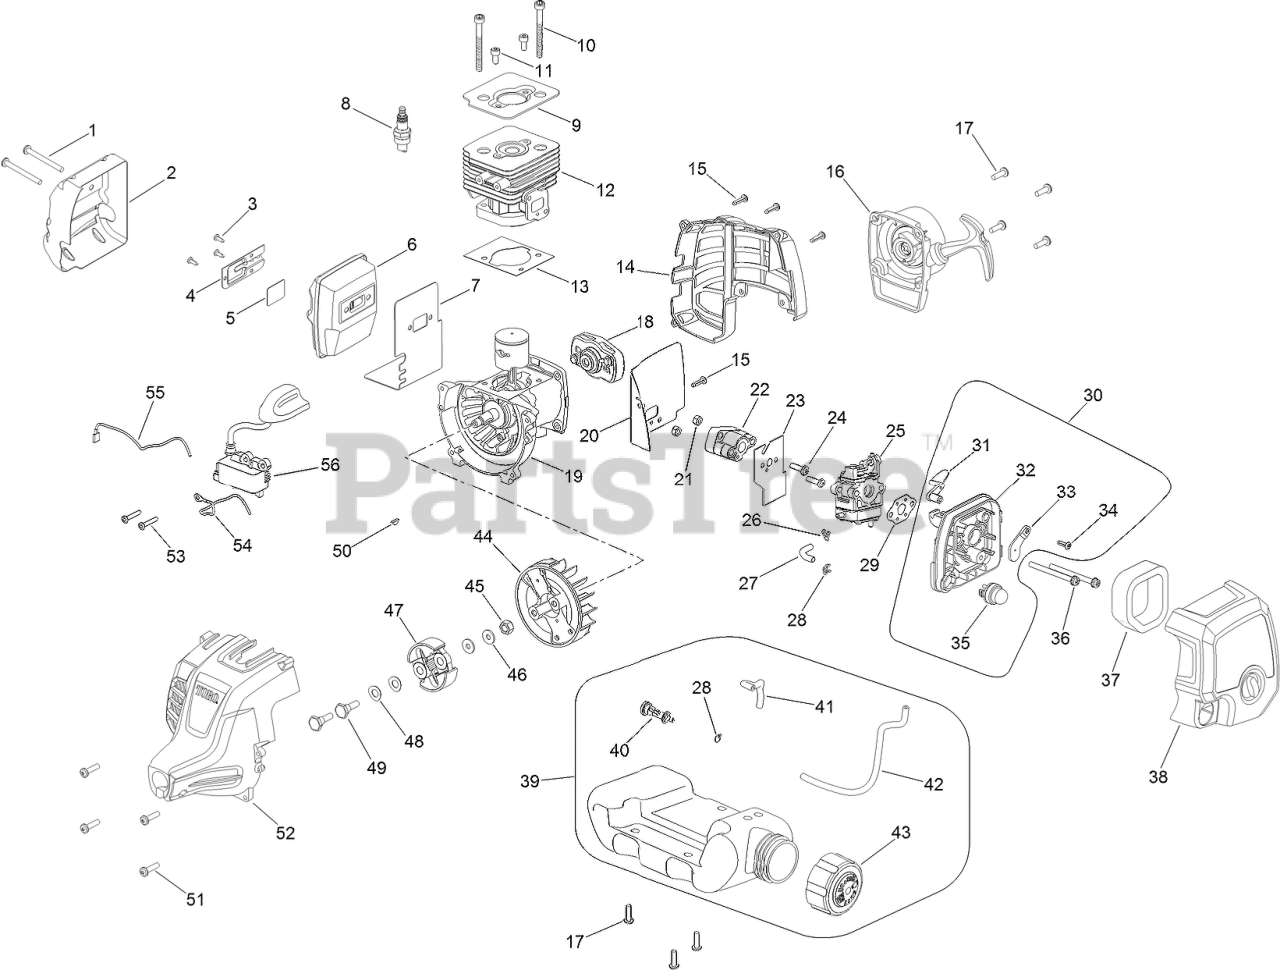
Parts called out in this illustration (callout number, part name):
1	SCREW-PAN HD
2	SHIELD-HEAT
3	SCREW-PAN HD
4	COVER-TRIMMER
6	MUFFLER ASM
7	GASKET-MUFFLER
8	SPARK PLUG
9	PLATE-CYLINDER
10	SCREW-SOCKET HEAD
11	SCREW-PAN HEAD, TORX
12	CYLINDER
14	HOUSING-ENGINE, REAR
15	SCREW
16	RECOIL STARTER ASM
17	SCREW-PAN HD
18	PULLEY ASM
19	CRANKCASE ASM
20	GASKET-INSULATOR
22	INSULATOR-DAM, HEAT
24	SCREW-PAN HD
25	CARBURETOR ASM
26	CLIP-HOSE
27	LINE-FUEL, 45MM
28	CLIP-HOSE
29	GASKET-CARBURETOR
30	FILTER HOUSING ASM
31	LEVER-CHOKE
32	PLATE-CARBURETOR
33	PLATE-CHOKE
34	SCREW-PAN HD
35	PRIMER ASM
36	SCREW-PAN HD
37	ELEMENT
38	COVER-INTAKE, AIR
39	FUEL TANK ASM
40	FILTER-FUEL
41	HOSE-FUEL
42	HOSE-FUEL
43	CAP-FUEL
45	NUT-ROTOR
47	CLUTCH ASM
48	WASHER-CURVED
49	SCREW-CLUTCH
50	KEY-WOODRUFF
51	SCREW-PAN HD
52	HOUSING-ENGINE, FRONT
53	SCREW-PAN HD
54	WIRE-LEAD, RED
55	WIRE-LEAD, BLACK
56	COIL AND BOOT ASM
